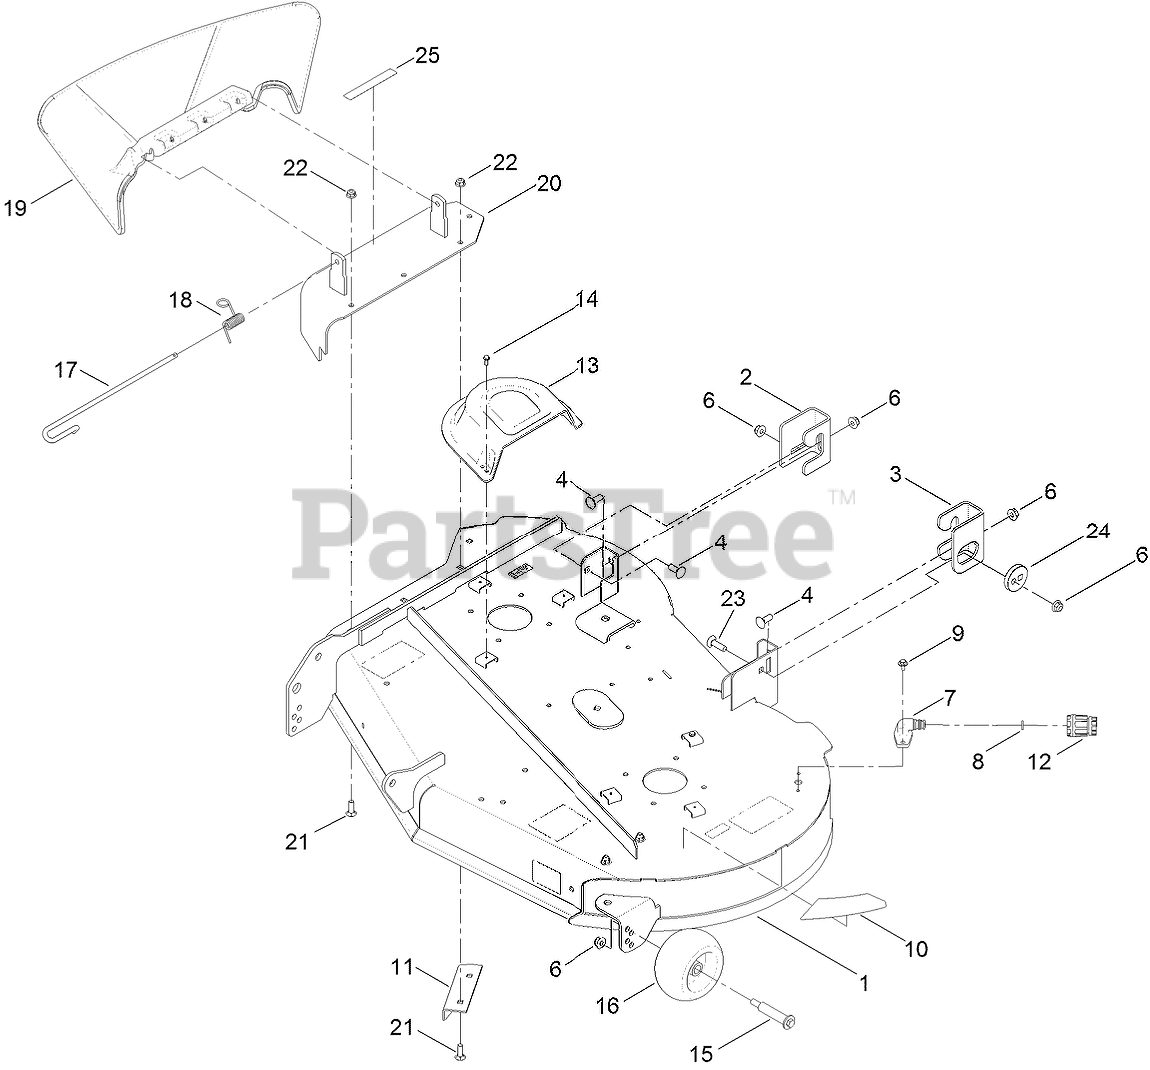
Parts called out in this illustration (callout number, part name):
1	42 INCH DECK AND DECAL ASM
2	BRACKET-HANGER, RH
3	BRACKET-HANGER, LH
4	BOLT-CARR
6	NUT-HF, NI
7	FITTING-WASHOUT
8	O-RING
9	SCREW-HHFTF
10	DECAL-DECK
11	BAFFLE-CUTOFF
12	CONNECTOR-HOSE
13	COVER-BELT
14	SCREW-TAPTITE
15	BOLT-SHOULDER
16	ROLLER-SCALP, ANTI
17	PIN-CHUTE
18	SPRING-TORSION
19	DEFLECTOR-DISCHARGE
20	DISCHARGE COVER ASM
21	SCREW-CARR
22	NUT-HF, NI
23	SCREW-CARR
24	ECCENTRIC
25	DECAL-DANGER
